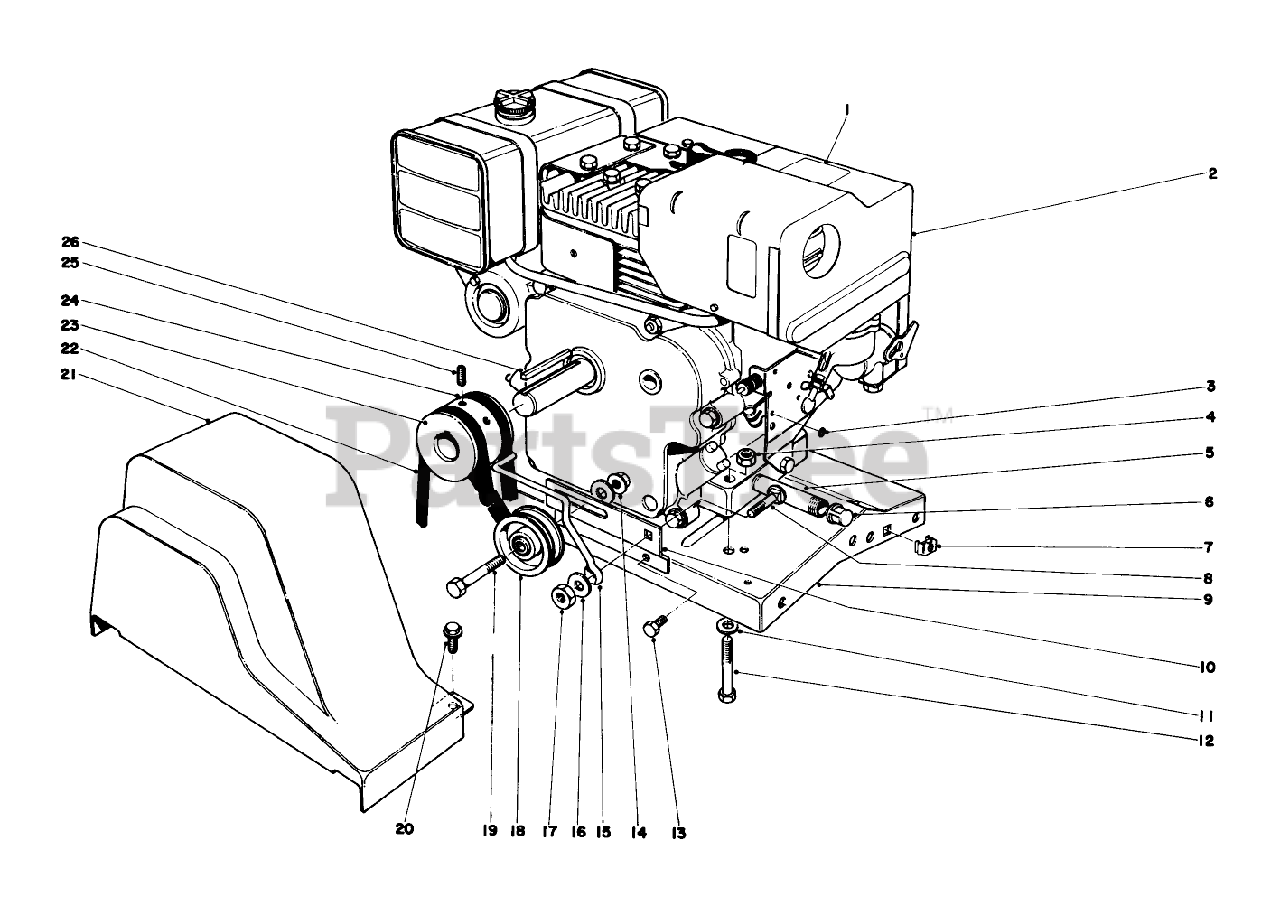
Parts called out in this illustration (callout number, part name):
1	Decal Instruction
2	Engine
3	WASHER-LOCK, INT
4	NUT-LOCK, CONE
5	NIPPLE-PIPE
6	CAP-PIPE
8	SCREW-CARR
11	WASHER-PLAIN
12	SCREW-HH
13	SCREW-HHFTF
14	NUT-HHF, WHIZ
15	BELT GUIDE
16	WASHER-FLAT
18	Idler Pulley
19	SCREW-HH
20	SCREW-HWH
24	V-BELT
